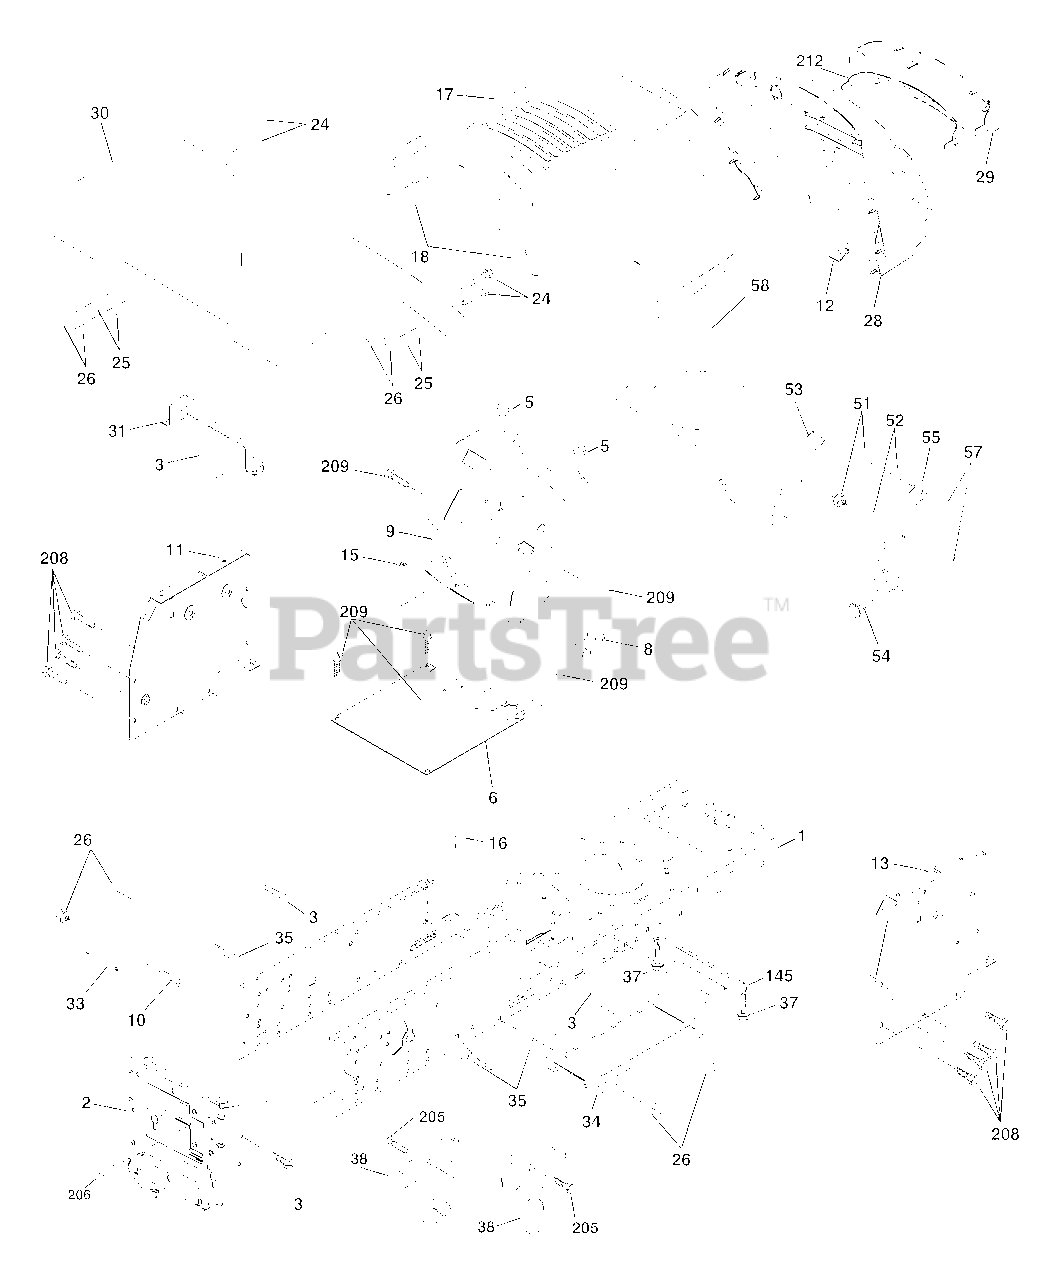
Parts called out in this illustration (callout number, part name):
1	Chassis
2	Drawbar, Stretch
3	Screw 3/8-16 x 3/4
5	Bumper, Hood/Dash
6	Saddle Silkscreen
8	Clip Retainer Slide-On
9	Dash
10	Bolt, Carriage 3/8-16 x 1
11	Panel Dash LH
12	Clip Tinnerman Grille P.L
13	Panel Slkscr Dash RH
15	Screw Mach TRHD 5/16-18uncx3/4
16	Nut Keps 5/16-18 Unc
17	Hood
18	Bumper Hood
24	Bolt Fin Hex 3/8-16unc X 1 Gr. 5
25	Washer 13/32 X 13/16 X 12 Ga
26	Nut Lock Hex w/Ins 3/8-16 Unc
28	Grille/Lens Asm.
29	Lens Grille Private Label
30	Fender
31	Bracket Fender Repl 109873x
33	Footrest Pnt LH
34	Footrest Pnt RH
35	Bolt Rdhd Sht Sqnk 3/8-16 X3/4
37	Screw Thdrol 5/16-18 x 1/2 TYT
38	Bracket Asm. Pivot Mower
51	Nut Lock W/Insert 1/4-20unc
52	Washer 9/32 x 7/8x16 Ga.
53	Bracket Grille Lh
54	Screw Hex 8-18 x 7/8
55	Bracket Grille Rh
57	Bolt Fin Hex 1/4-20 unc x .75
58	Duct Air Engine PL/LT
145	Rod Pivot Chassis/Hood
205	Screw Thdrol 3/8-16 x 1/2
206	Bolt Shoulder 5/16-18
208	Screw Thdrol 3/8-16 x 1/2
209	Screw Hex Wsh Thdrol 3/8-16
212	Insert Lens Reflect
